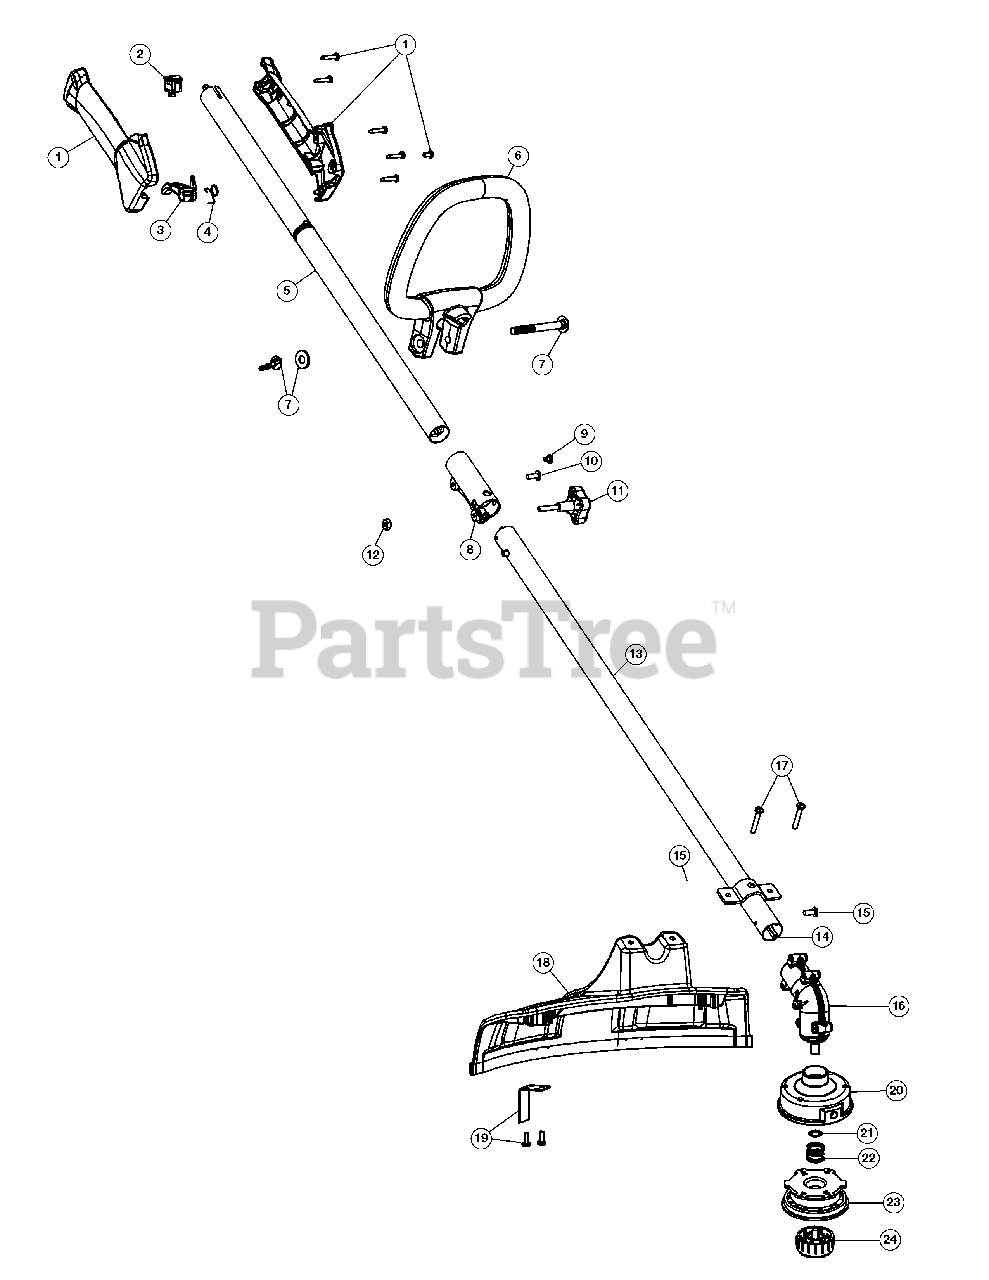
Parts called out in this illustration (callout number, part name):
1	Throttle Housing Assembly (Incl. 2-4)
3	Throttle Trigger
4	Throttle Trigger Spring
5	Upper Drive Shaft Housing Assembly
6	D-Handle (Incl. 7)
7	D-Handle Hardware Assembly
8	Split Boom Coupler (Incl. 9-12)
11	Adjustment Knob (Incl. 12)
12	Knob Retaining Nut
13	Lower Drive Shaft Housing Assembly
14	Lower Flexible Drive Shaft
15	Anti-Rotation Screw
16	Gear Box Assembly (Incl. 15 & 20-24)
17	Shield Mounting Screws
18	Shield Assembly (Incl. 17 & 19)
19	Blade Assembly
20	Outer Spool Assembly
23	Inner Reel
24	Bump Knob Assembly
